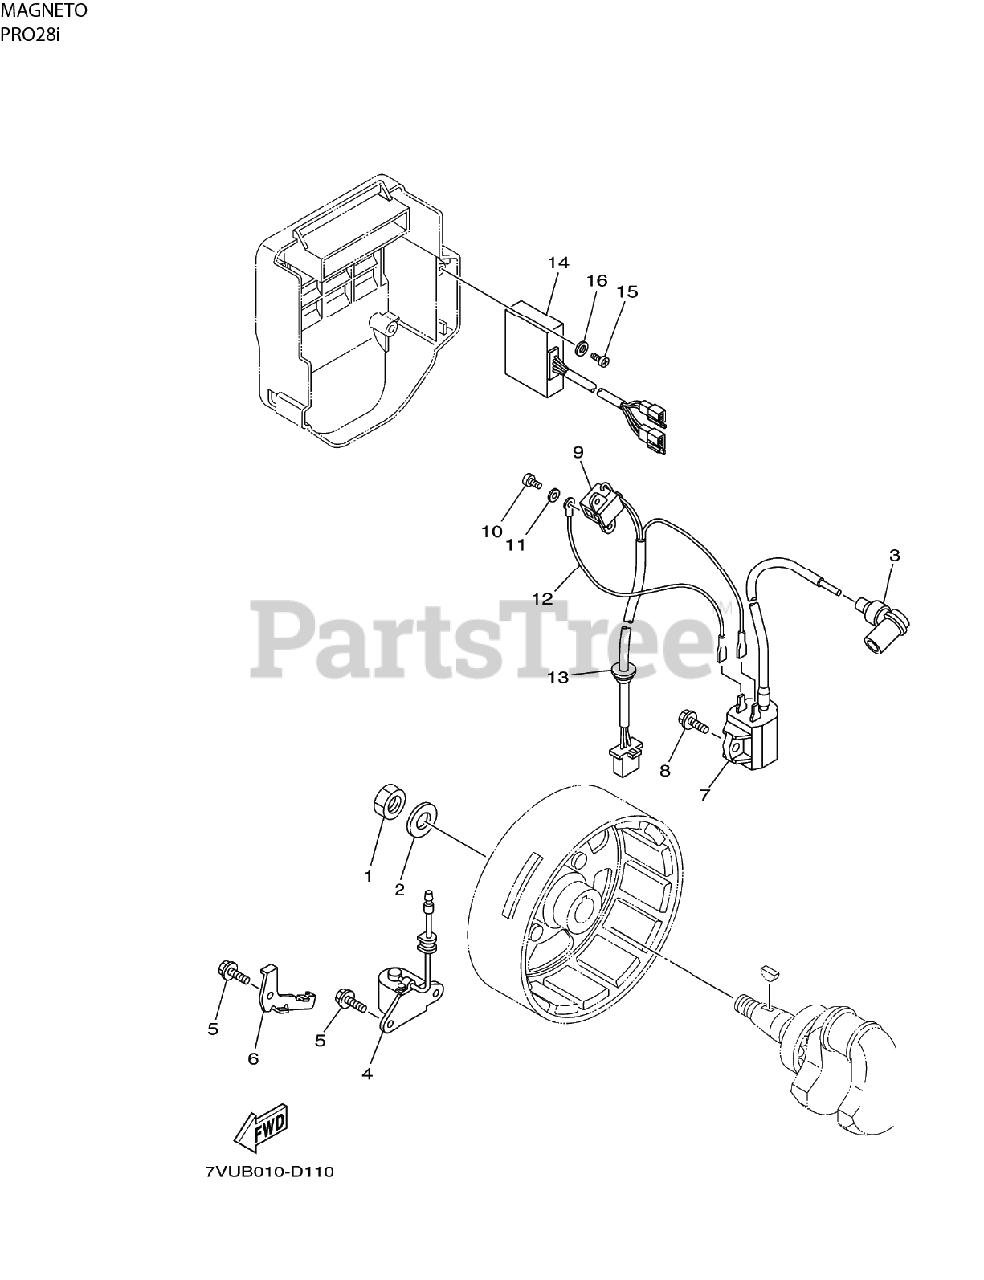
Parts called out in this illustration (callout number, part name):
3	CAP, PLUG ASSEMBLY
4	SWITCH, OIL LEVEL GAUGE ASSEMBLY
5	SCREW - BOLT FLANGE
7	COIL, IGNITION ASSEMBLY
8	SCREW - BOLT
9	TRIGGER ASSEMBLY - COIL PULSER
10	SCREW - PAN HEAD
11	WASHER, PLATE
12	LEAD, WIRE SUB-LEAD
14	MODULE - C.D.I. UNIT ASSEMBLY
15	SCREW - TAPPING
16	WASHER, PLATE
